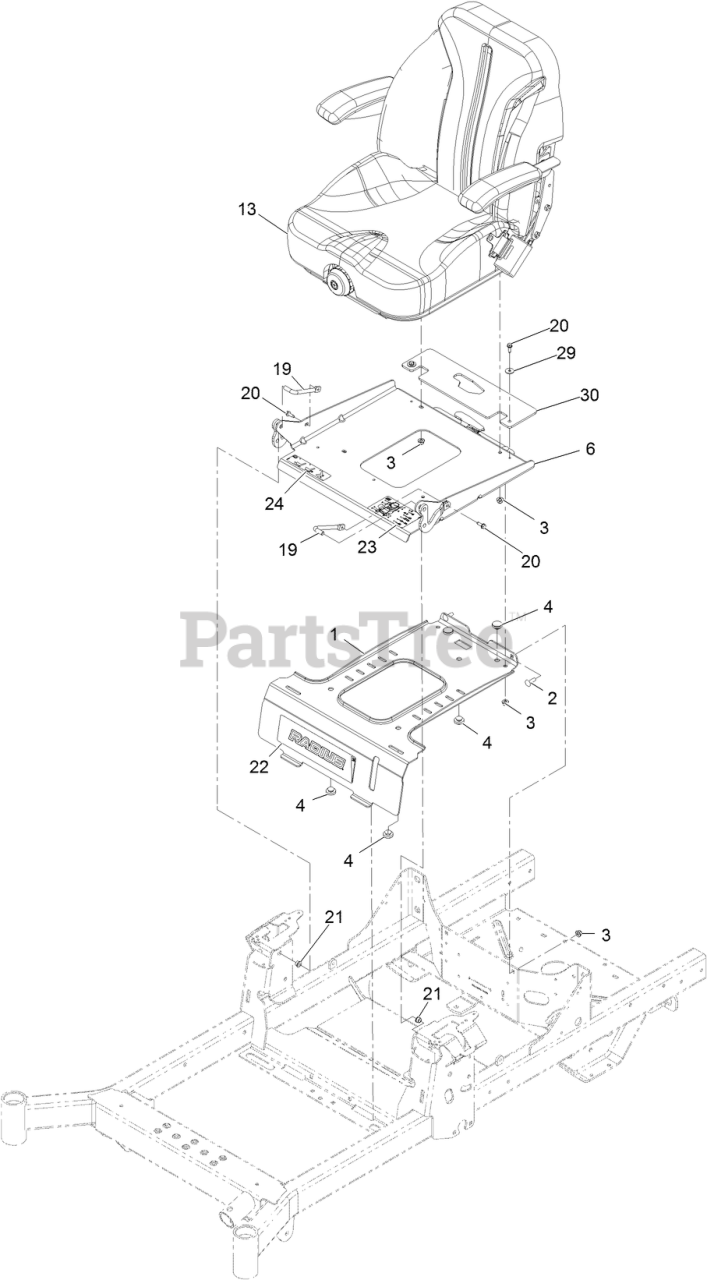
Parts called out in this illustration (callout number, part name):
1	PLATE-RETAINER, TANK
2	SCREW-CARR
3	NUT-HF, NI
4	BUMPER-SEAT
6	SEAT PAN AND LATCH ASM
13	ASM-SUSP SEAT
19	PIN-PIVOT, SEAT
20	SCREW-HWH, THREAD ROLL
21	BUSHING-FLANGED
22	DECAL-RADIUS LOGO
23	DECAL-AID, SERVICE
24	DECAL-LATCH, SEAT
30	GUARD-SEAT, RUBBER
